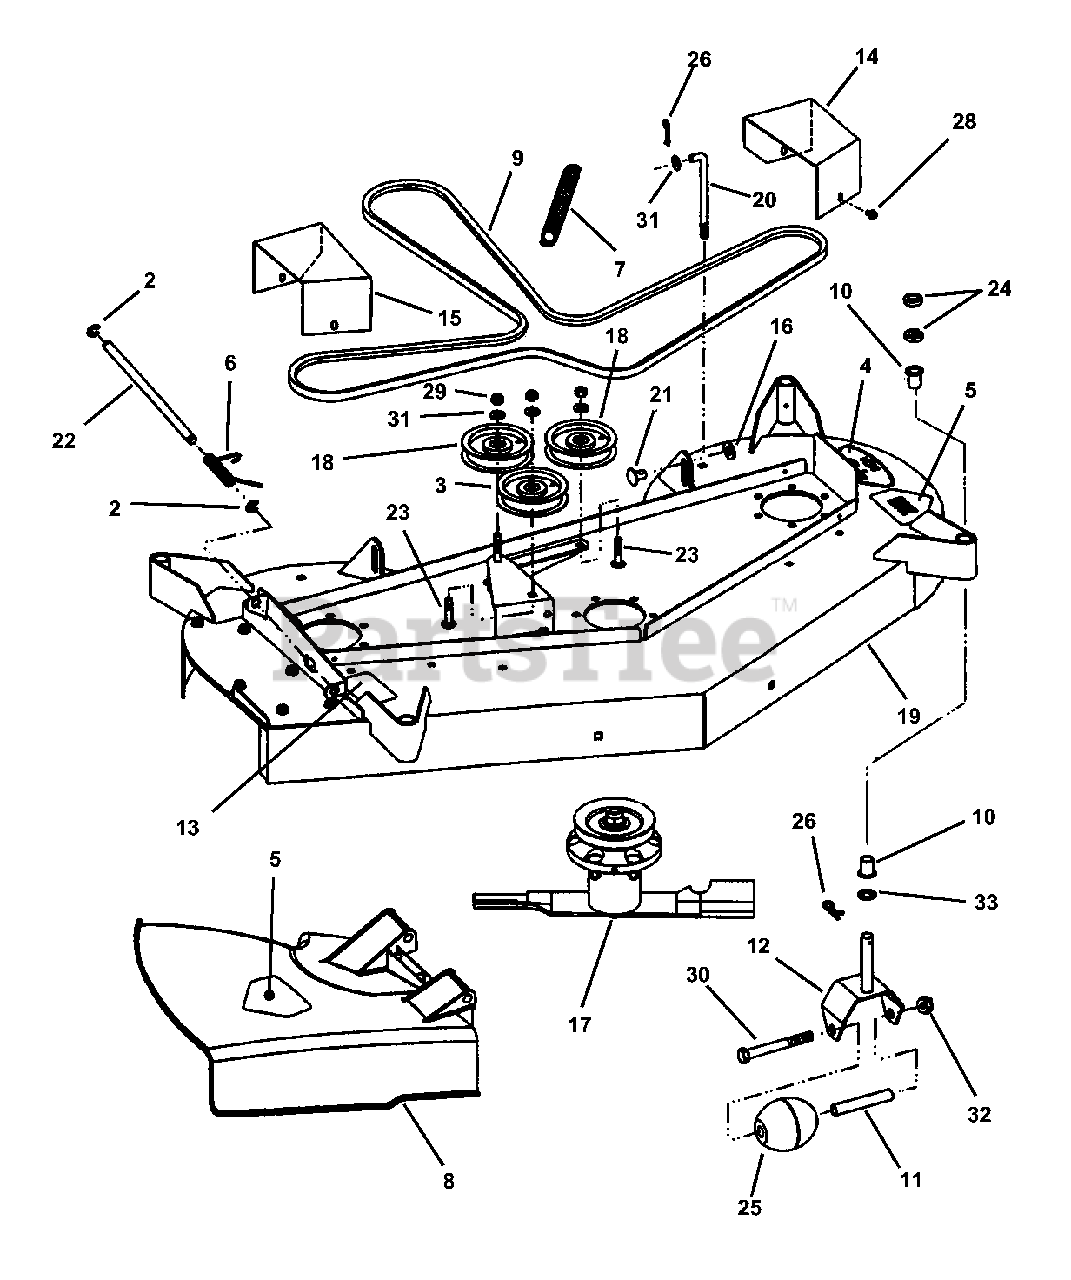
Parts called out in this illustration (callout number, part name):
2	RING, External Retaining
3	IDLER, 4.12" Flat
4	DECAL, 48" Deck
5	DECAL, CPSC
6	SPRING, Chute
7	SPRING, Idler Primary
8	CHUTE, Side Discharge
9	V-BELT, HA Section,
10	BEARING, 1/2 x 3/4" Plastic
11	SLEEVE, Caster Wheel
12	WELDMENT, Bracket/Shaft Caster
13	DECAL, Chute/Deflector
14	COVER, Belt L.H.
15	COVER, Belt R.H.
16	WASHER, 1/2" Flat
17	ASSEMBLY, 48" Spindle
18	IDLER, 3-1/4" Flat
19	ASSEMBLY, 48" Painted Mower Deck
20	LINK, Leveling
21	SUPPORT, Swivel
22	HINGE PIN, Chute
23	BOLT, 3/8-16 x 1-3/4" Short Neck Carriage, Grade 5
24	SPACER, Blade
25	ROLLER, Low Density Polyethylene
26	HAIR PIN, 3/32 x 1-1/2"
28	SCREW, 1/4-20 x 3/8" Hex Washer Self-Tap
29	NUT, 3/8-16 Hex Center Lock, Grade 5 or B
30	SCREW, 1/2-20 x 4-1/2" Hex Head Cap, Grade 5
31	WASHER, 3/8" Flat
32	NUT, 1/2-20 Hex Center Lock,
33	WASHER, .64 I.D. Flat
